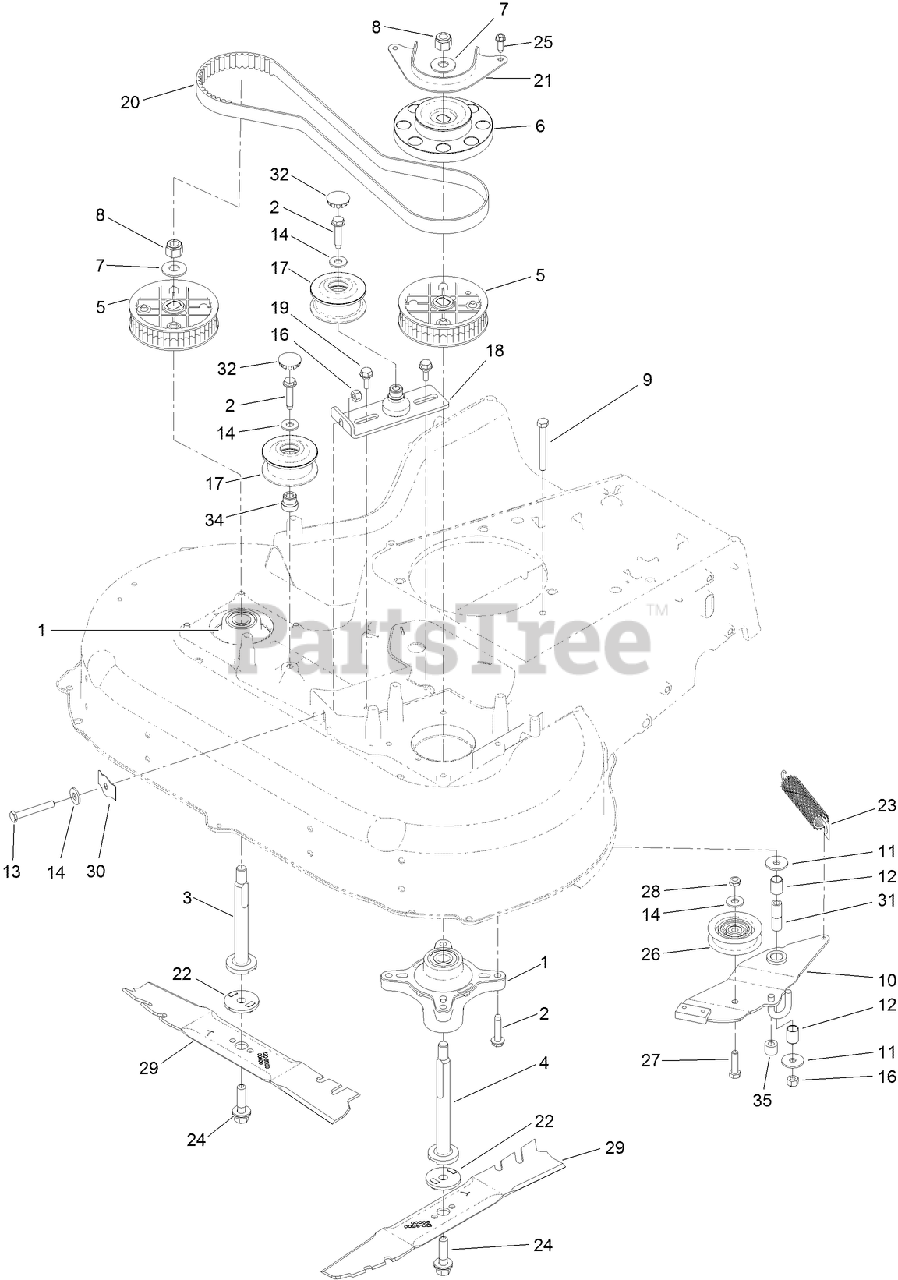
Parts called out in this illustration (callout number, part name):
1	SPINDLE ASM
3	SHAFT-SPINDLE
4	SHAFT-SPINDLE
5	SPROCKET
6	PULLEY-BRAKE, SPINDLE
7	WASHER-SPRING
8	NUT-HEX
9	SCREW-HH
10	BRAKE ARM ASM
11	WASHER-PIVOT
12	Bushing-Sleeve
13	BOLT-TAP, HH
14	WASHER-FLAT
16	NUT-LOCK, NI
17	FLAT IDLER PULLEY ASM
18	BRACKET-IDLER
19	SCREW-SHOULDER, HHF
20	BELT-SYNCHRONOUS
21	GUIDE-BELT, SPINDLE
22	ADAPTER-BLADE
23	SPRING-EXTENSION, BRAKE
24	BOLT-BLADE
25	SCREW-HWHTF
26	PULLEY-IDLER
27	SCREW-HH
28	NUT-LOCK, NI
29	BLADE-ATOMIC, 15.4 INCH
30	SPRING-FLAT
31	Spacer-Brake
32	PLUG-BUTTON
34	ADAPTER-BORE
35	HOSE-COOLANT
